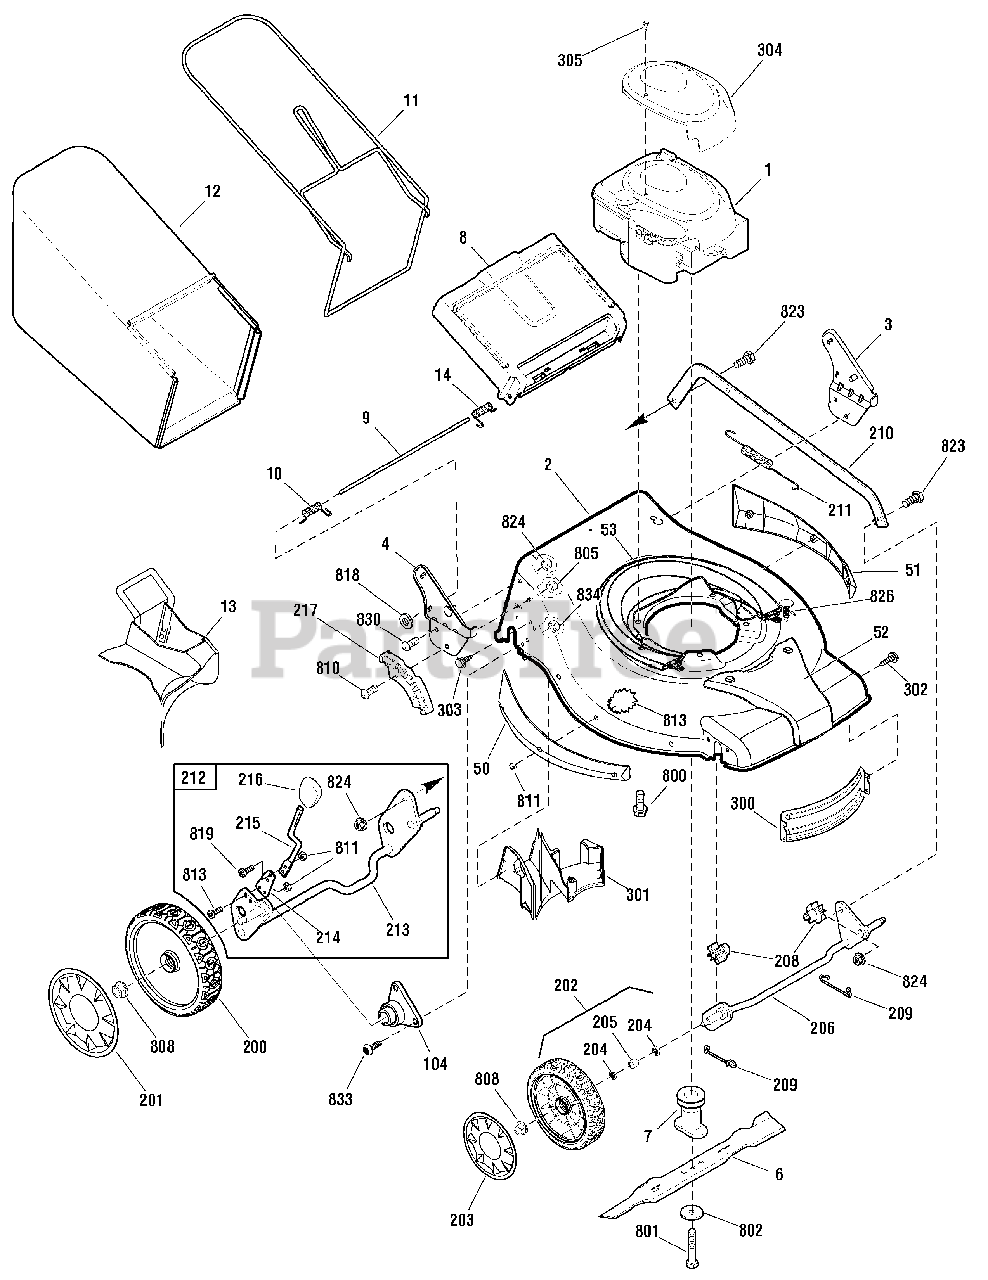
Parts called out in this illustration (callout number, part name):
1	* ENGINE, B&S 550 Series EU
2	MOWER HOUSING
3	BRACKET ASSEMBLY, Left Handle
4	BRACKET ASSEMBLY, Right Handle
6	BLADE, 19"
7	BLADE ADAPTER ASSEMBLY
8	DOOR, Rear
9	ROD, Rear Door
10	SPRING, Torsion Rear Door, Right
11	FRAME ASSEMBLY
12	BAG ASSEMBLY
13	MULCH PLUG
14	SPRING, Torsion Rear Door, Left
50	SIDE GUARD, Right
51	SIDE GUARD, Left
52	HOUSING COVER, Front
53	HOUSING COVER, Rear
104	SLEEVE ASSEMBLY, Rear Axle
200	WHEEL ASSEMBLY, Rear, Push, Ball Bearing, 200MM (7.1"), Tread III, SL
201	HUBCAP, Rear
202	WHEEL, Front, Complete
203	HUBCAP, Front
204	WHEEL BEARING (Not Available)
205	SPACER (Not Available)
206	CROSSBAR ASSEMBLY, Front
208	BUSHING, Front Crossbar
209	SPRING, Clip Crossbar
210	LINK, Single Lever
211	SPRING, Extension
212	CROSSBAR ASSEMBLY, Rear (Not Available)
213	REAR CROSSBAR
214	SPRING, Adjuster
215	LEVER, Height Adjustment
216	KNOB, Adjuster
217	BRACKET, Height Adjuster
300	BAFFLE, Front
301	BAFFLE, Rear
304	SHROUD, With Label
305	SCREW, Machine Hex Washer Head
800	SCREW, Hex Head, 3/8-16 x 1
801	BOLT, Blade, 3/8-24 x 2
802	WASHER, Belleville
805	NUT, Nylock, M8 x 1-1/4
808	NUT, Flange, 3/8-16
810	BOLT, Hex Key Head
811	NUT, Nylock
813	SCREW, Torx Head, M5 x .8 x 14mm
818	PUSHNUT, 1/4
819	SCREW, Torx Head, M5 x .8 x 12.5mm
823	BOLT, Shoulder, 5/16-18 x 1
824	Nut, Flange, 5/16-18
826	SCREW, 1/4-20 x 7/8
830	SCREW , 5/16-18 x 3/4
833	SCREW, Torx, 1/4-20 x 5/8
900	SPRING CLIP, Rear Door
